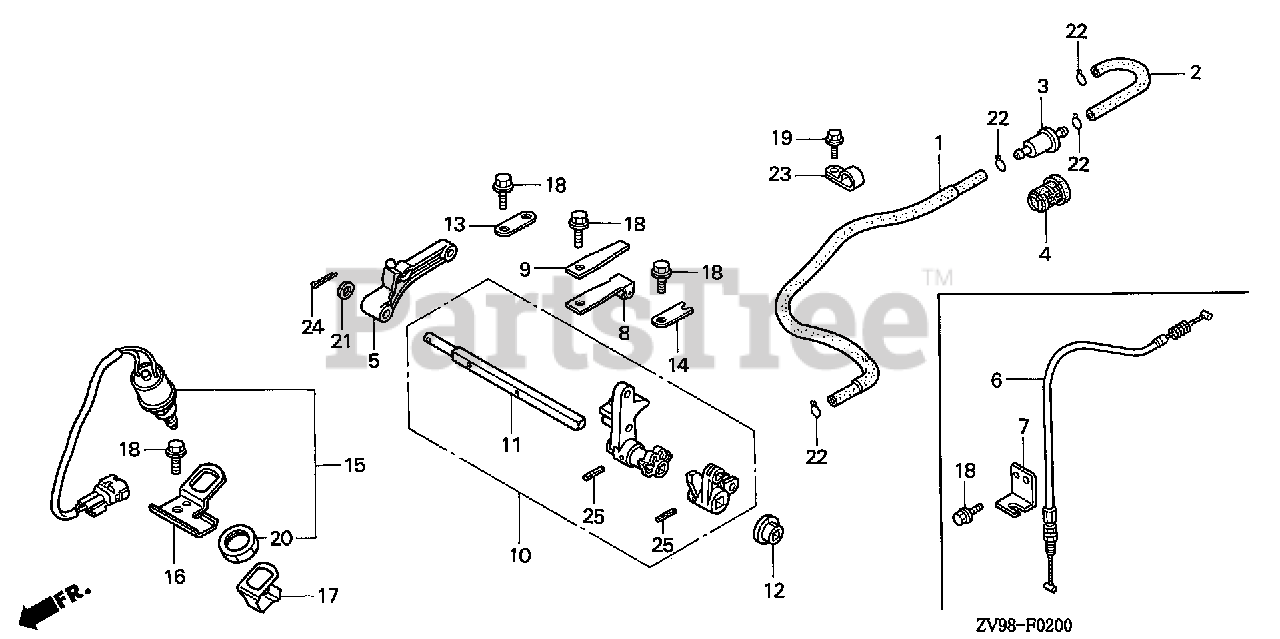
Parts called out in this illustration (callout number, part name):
1	TUBE, FUEL
2	TUBE B, FUEL
3	FILTER, FUEL
4	SUSPENSION, STRAINER
5	ARM, THROTTLE
8	SPRING, CLICK
9	SPRING, CLICK ASSIST
10	SHAFT, SHIFT
11	SHAFT, SHIFT
12	BUSH, SHAFT
13	PLATE, SHIFT
14	PLATE, SHIFT SHAFT
15	SWITCH SET, NEUTRAL
15	SWITCH ASSY., NEUTRAL
16	BRACKET, NEUTRAL SWITCH
17	PLATE, NEUTRAL SWITCH
18	BOLT, FLANGE (6X12)
19	BOLT, FLANGE (5X10)
20	NUT, HEX. (20MM)
21	WASHER (7.5MM)
22	CLIP, TUBE (B10)
23	CLIP (14MM)
24	PIN, SPLIT (2.0)
25	PIN, SPRING (3X20)
